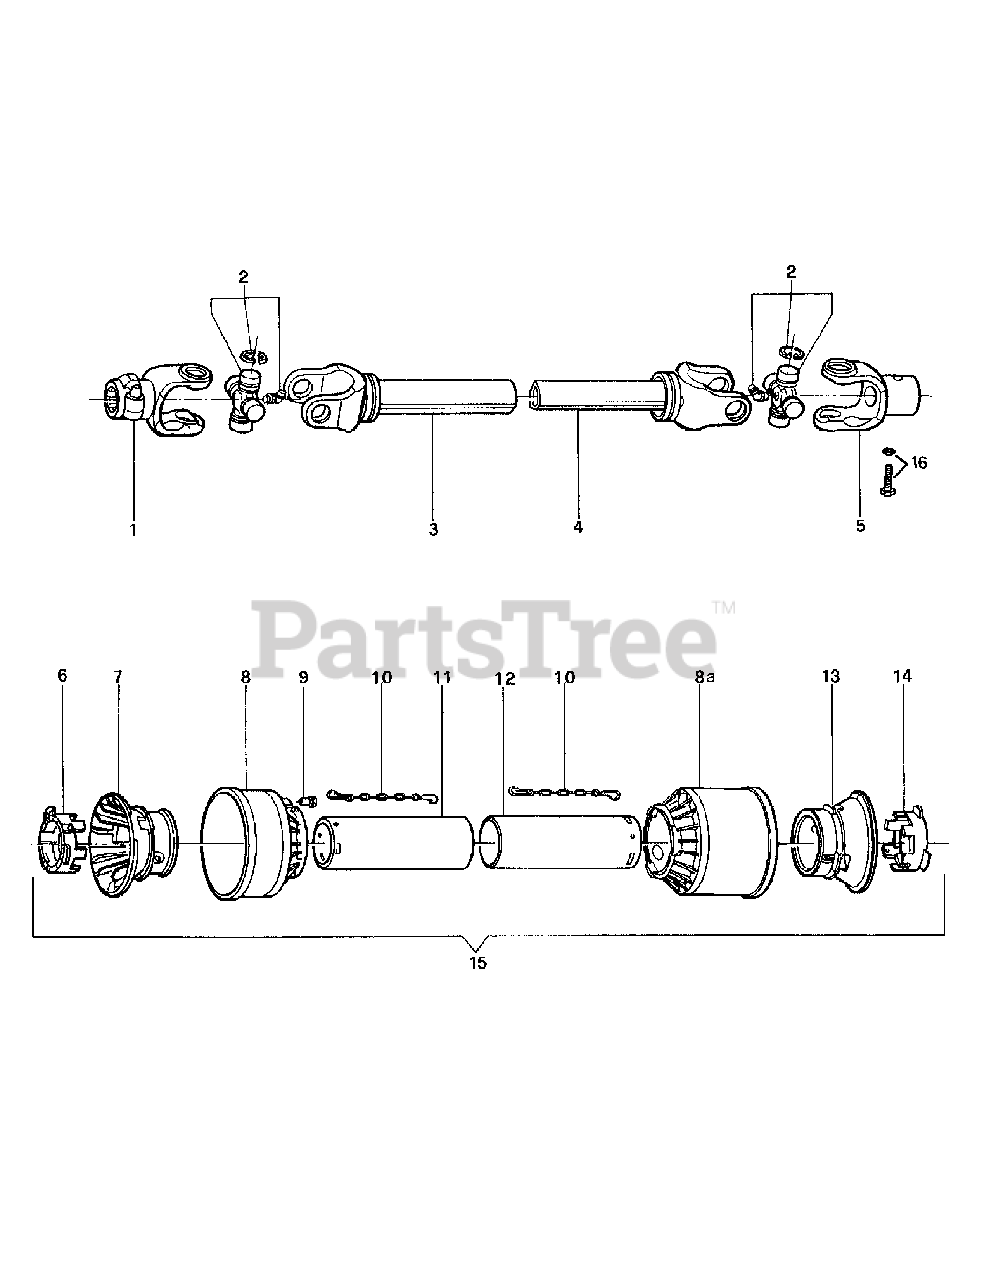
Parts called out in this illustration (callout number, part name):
1	Yoke assembly (tractor end)
2	Cross & bearing
3	Outer tube with yoke (RC60)
3	Outer tube with yoke (RC72)
4	Inner tube with yoke (RC60)
4	Inner tube with yoke (RC72)
5	Yoke assembly (implement end)
6	Outer tube bearing
7	Outer tube rigid cone
8	Soft cone
9	Pin
10	Chain
11	Outer shield (RC60)
11	Outer shield (RC72)
12	Inner shield (RC60)
12	Inner shield (RC72)
13	Inner shield rigid cone
14	Inner tube bearing
15	Complete protection (RC60)
15	Complete protection (RC72)
16	Shear bolt ½"x3½" w/nut grade 2
